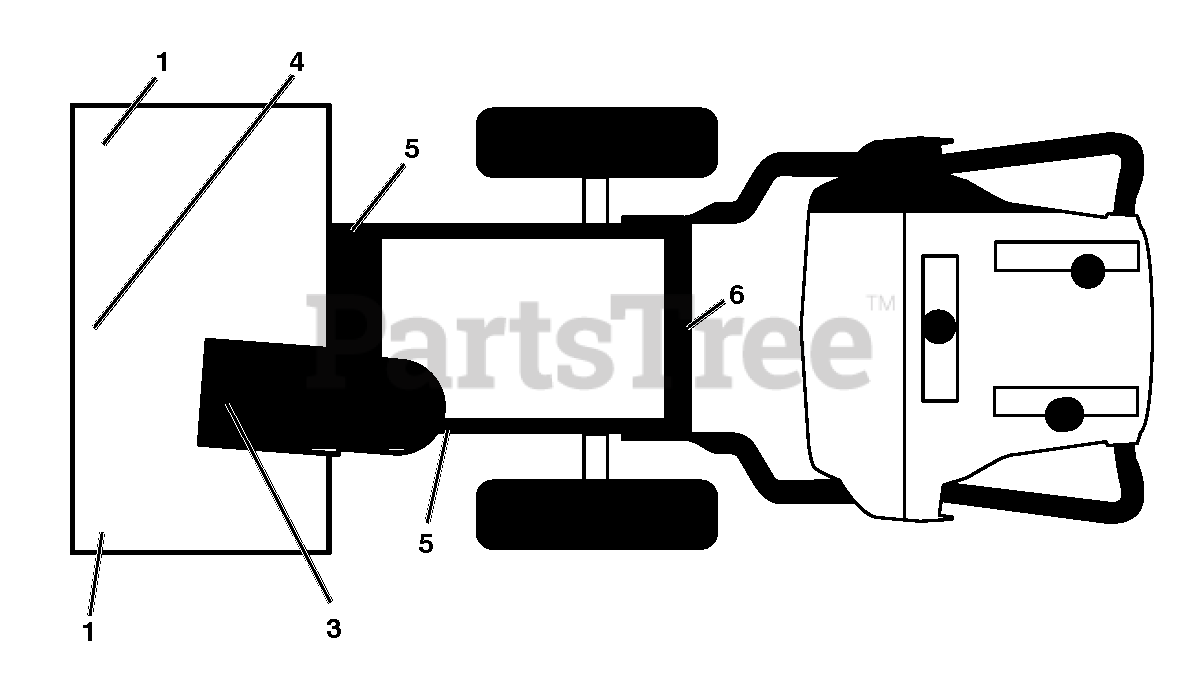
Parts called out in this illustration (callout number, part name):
1	DECAL.AUGER.SAFETY.
3	DECAL.CHUTE.SAFETY.
4	DECAL.AUGER."
5	DECAL.BELT.GUARD.
6	DECAL.FENDER
